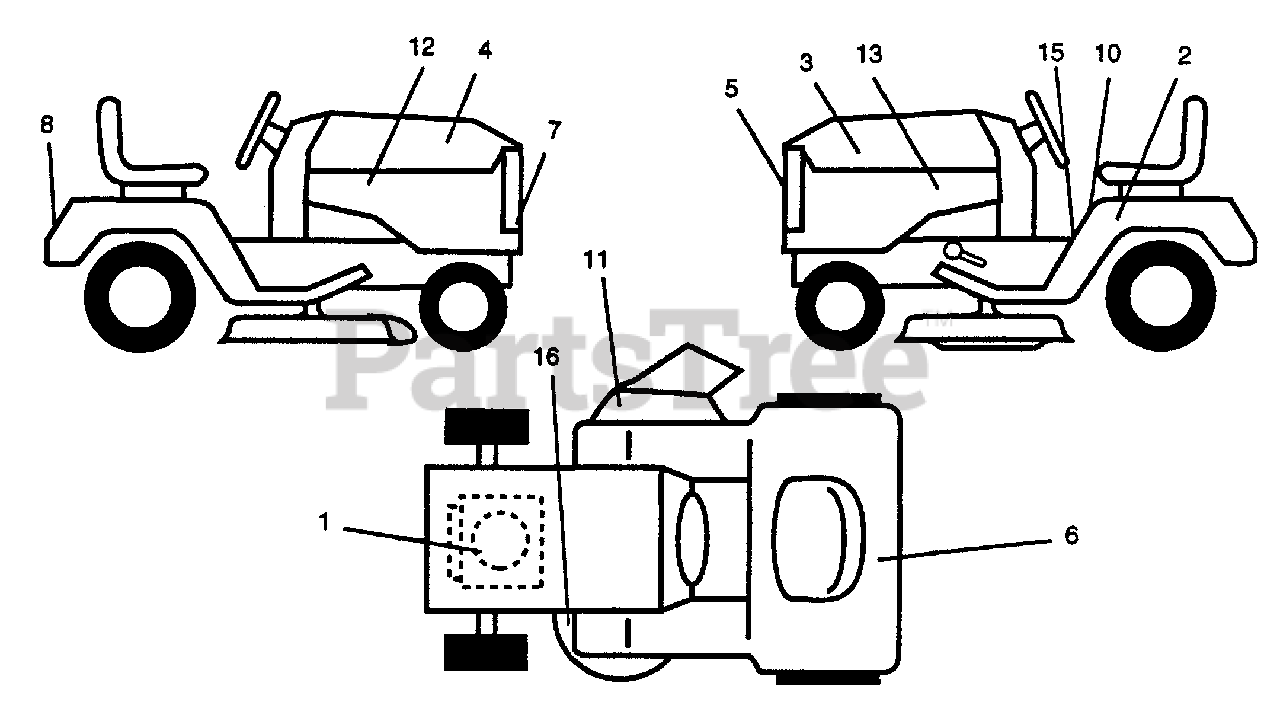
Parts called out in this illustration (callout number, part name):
1	Decal, Engine, HP
2	Decal, Indicator
3	Decal, Hood, L.H.
4	Decal, Hood, R.H.
5	Decal, Logo, Grill
6	Decal, Caution Battery
7	Decal, Lightbox
8	Decal, Logo, Fender
10	Decal, Fender, Caution
11	Decal, Warning, Multi-Language
12	Decal, Hood, Insert, R.H.
13	Decal, Hood, Insert, L.H.
15	Decal, Instruction, Operating
16	Decal, V-Belt Schematic
